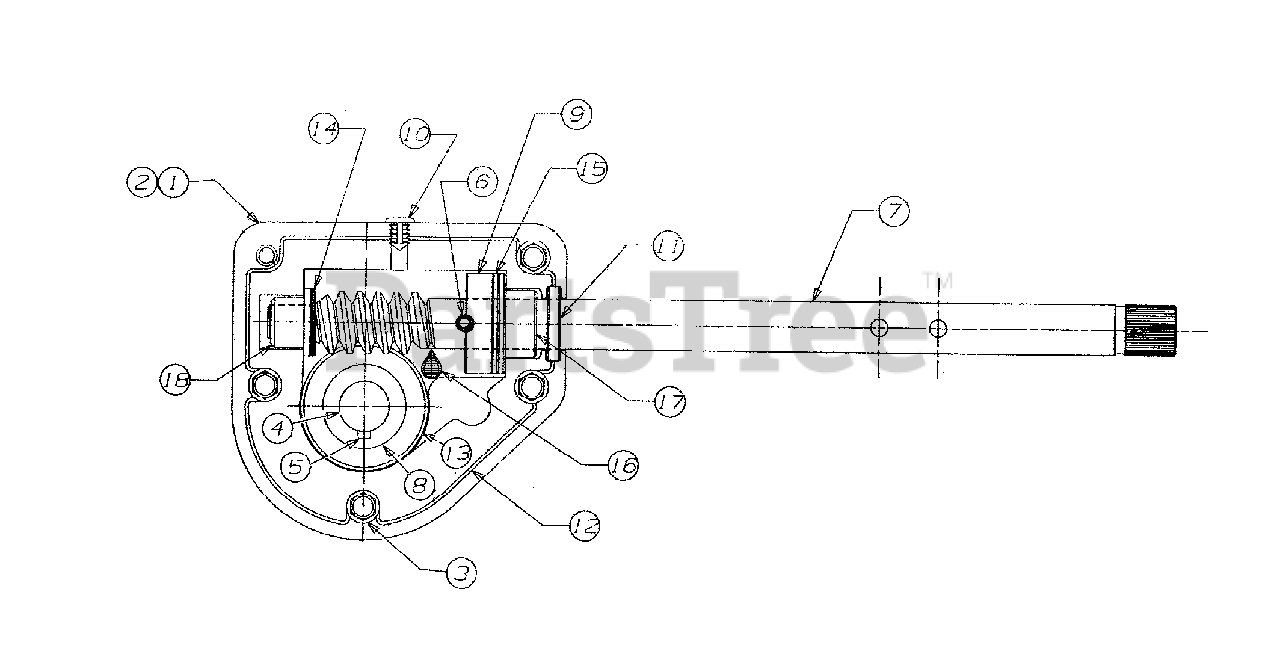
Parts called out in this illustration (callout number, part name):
1	Housing - L.H.
2	Housing - R.H.
3	Screw
4	Spiral Axle 22"
5	Key
6	Pin - Spiral
7	Shaft - Worm
8	Gear - Worm
9	Collar - Thrust
11	Seal - Oil
12	Locktite 5699
13	Washer - Flat
14	Washer - Flat
15	Washer - Flat
16	Grease
17	Bearing - Flange
18	Bearing - Flange
